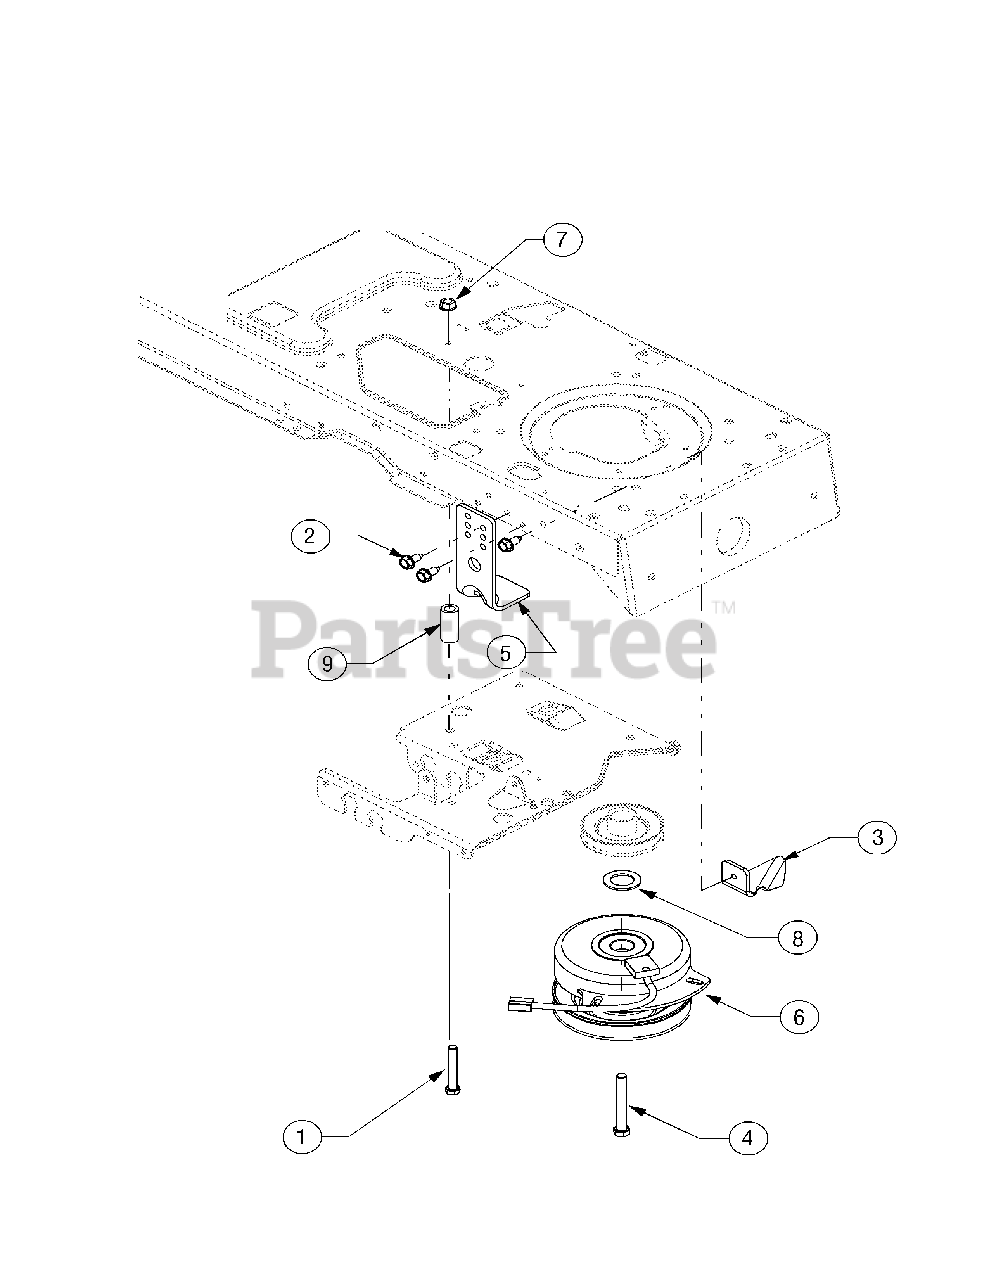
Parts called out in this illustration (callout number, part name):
1	Screw, 3/8-16 x 2.5 GR5
2	Screw, 5/16-12,.75
4	Screw, Hex Cap, 7/16-20 x 3.25 GR5
6	Clutch, Electric PTO
7	Nut, Hx. Nylon Lock, 3/8-16
8	Washer, Flat, 1.031 x 1.62 x.095
9	Spacer, 3/8 x 1.54
